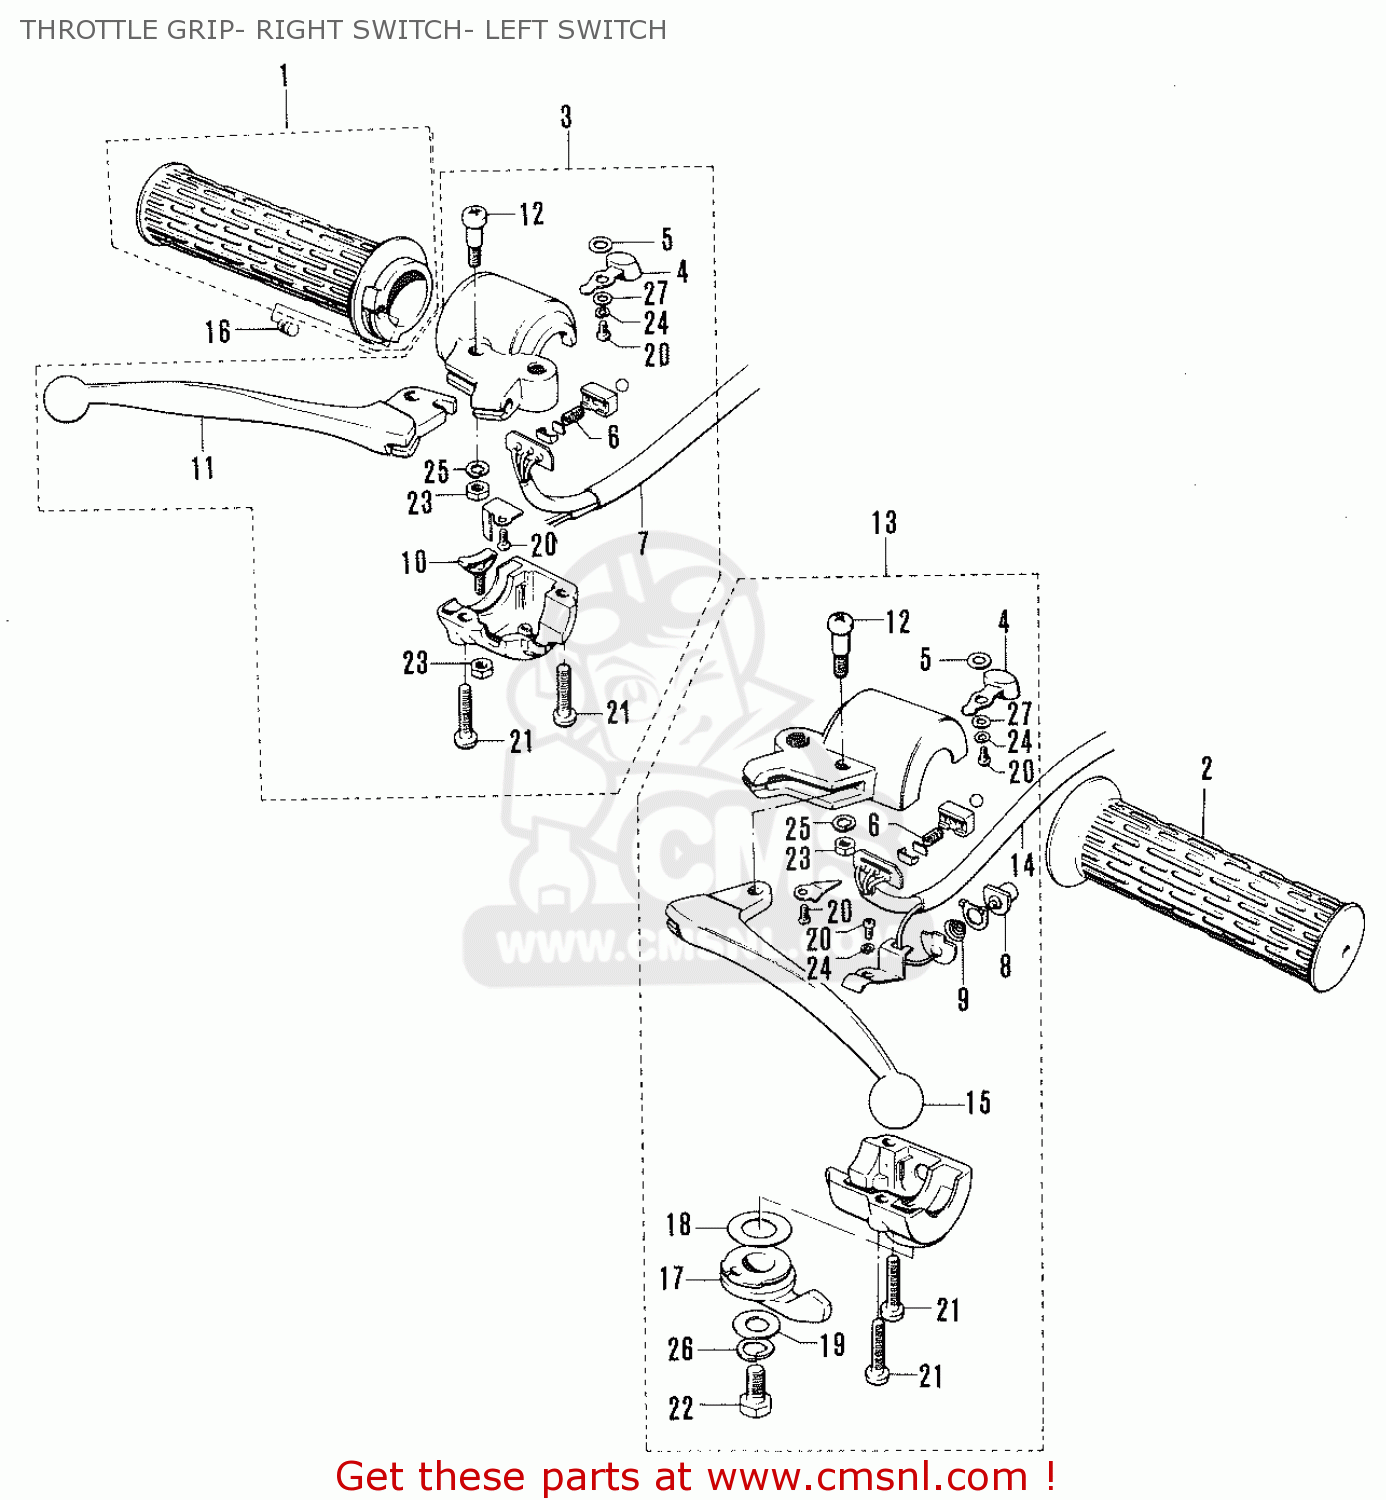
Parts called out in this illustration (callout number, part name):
1	GRIP,THROTTLE
2	GRIP,L
3	LEVER/SWITCH ASSEMBLY,BRAKE
4	KNOB,DIMMER SWITCH
5	WASHER,DIM SWITCH KNOB
6	SPRING,TURN SIGNAL SWITCH CONTACT
7	HARNESS,WIRING
8	BUTTON
9	SPRING
10	ADJUSTER,GRIP
11	LEVER,BRAKE
12	BOLT,LEVER
13	LEVER ASSEMBLY
14	WIRING HARNESS
15	LEVER,CLUTCH
16	PIECE,THROTTLE END
17	LEVER,STARTER
18	WASHER,ADJUSTER
19	WASHER,STARTER LEVER
20	SCREW
21	SCREW
22	BOLT
23	NUT
24	LOCK WASHER
25	LOCK WASHER
26	LOCK WASHER
27	WASHER
